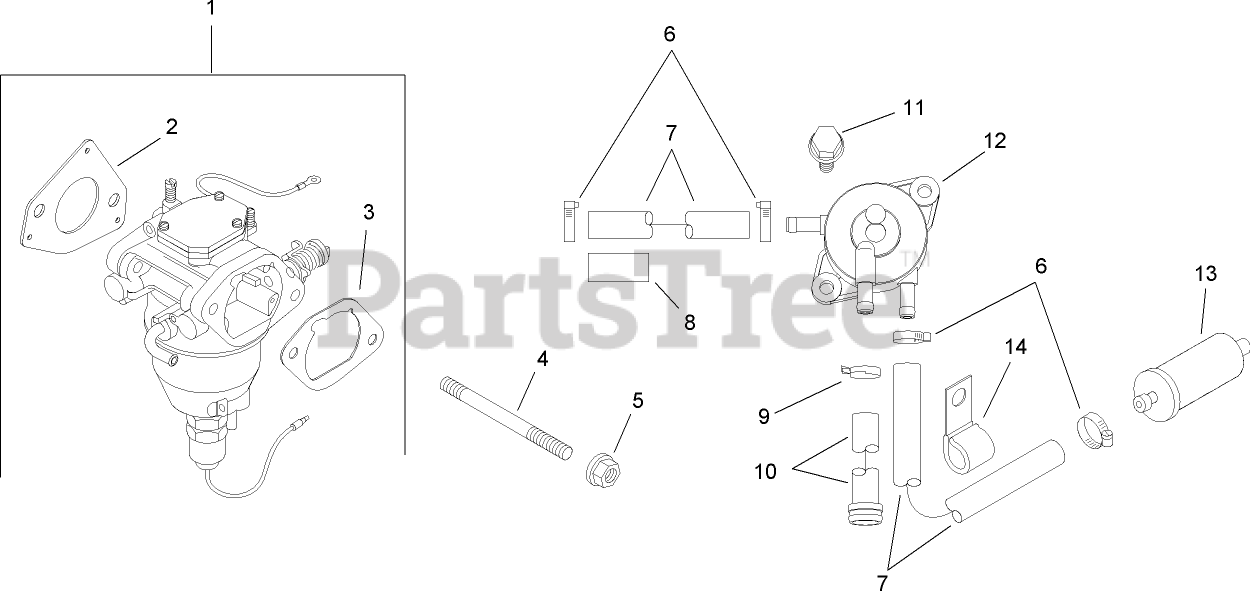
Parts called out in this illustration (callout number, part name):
1	Carburetor Kit w/Gaskets (Includes?2-3)
2	Gasket-Carburetor
3	Gasket-Air Cleaner Base
4	Stud-Carburetor
5	Nut-Hex Flange (M6x1.0)
6	Clamp-Hose
7	Line-Fuel (24 Inch, Cut?to?needed?length)
8	Sleeve-Antiabrasion
9	Clamp-Hose
10	Hose-Fuel Pump
11	Screw-Hex Cap (M6x1.7x18)
12	Pump-Pulse Fuel
13	FILTER-FUEL
14	Clip-Cable
15	Service Choke Repair Kit
16	Service Gasket Repair Kit
17	Float Kit w/Gaskets
18	Solenoid Valve Kit w/Gaskets
19	Overhaul Kit w/Gaskets
20	Overhaul Kit w/Gaskets (Includes?Float?Kit)
21	Service Choke Repair Kit
22	Service Gasket Repair Kit
23	Solenoid Valve Kit w/Gaskets
